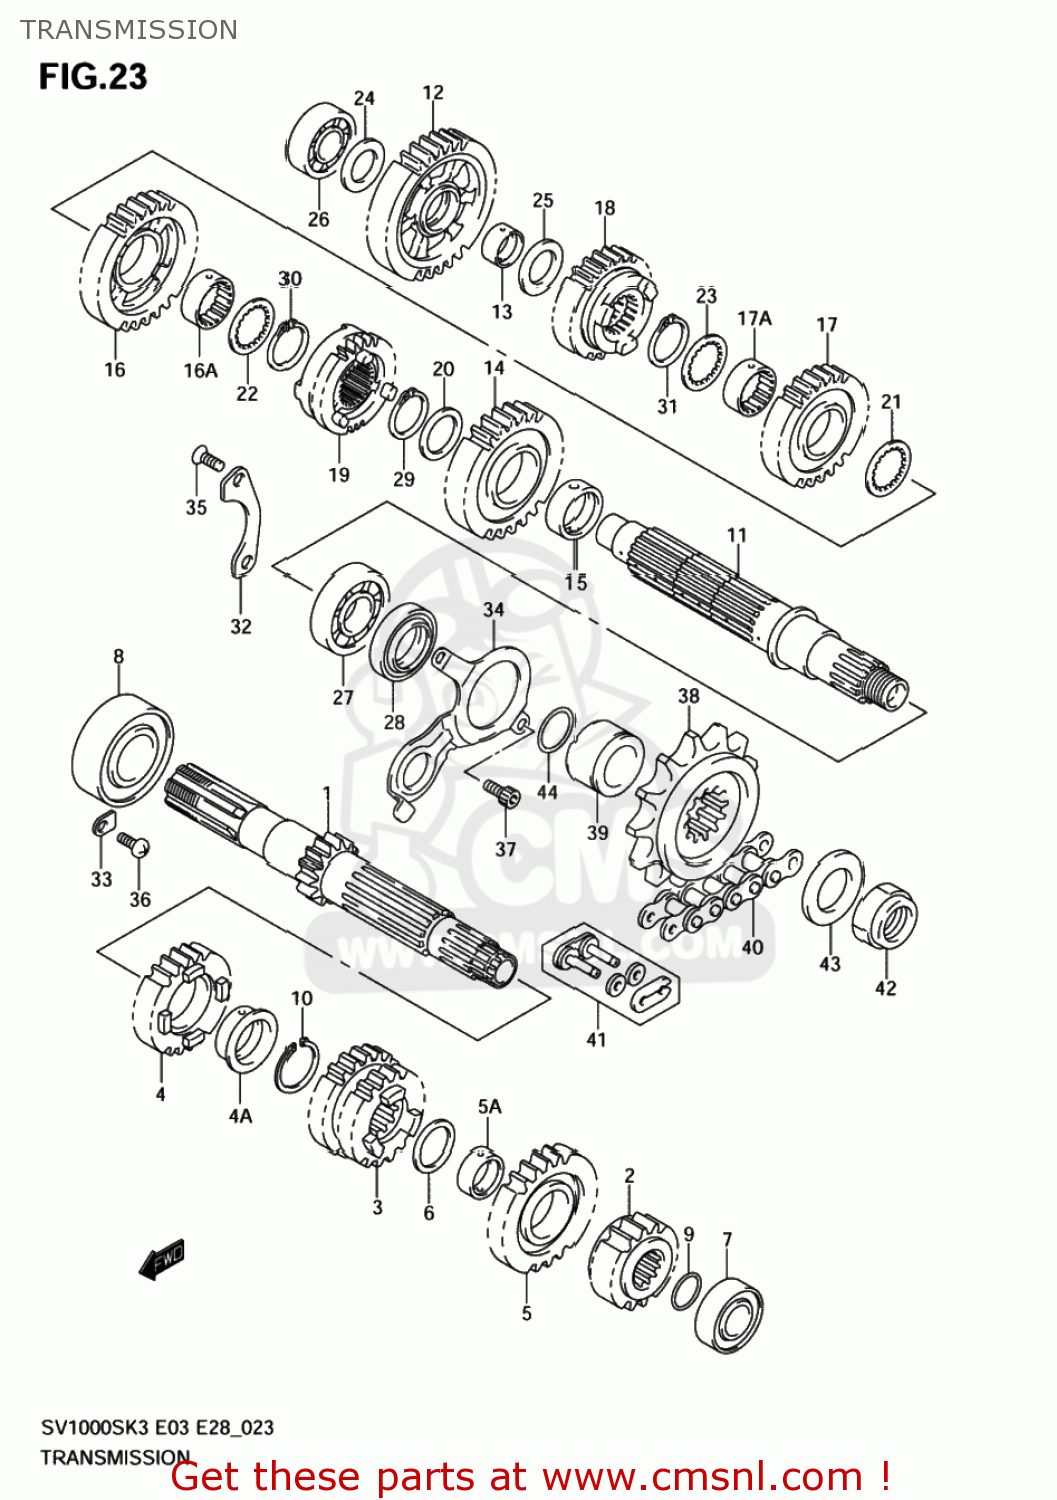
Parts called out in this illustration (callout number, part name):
1	SHAFT,COUNTER(NT:12)
2	GEAR,2ND DRIVE(NT:15)
3	GEAR,3RD & 4TH DRIVE(NT:18/22)
4	GEAR,5TH DRIVE(NT:23)
4A	BUSH,5TH DRIVE GEAR
5	GEAR,6TH DRIVE(NT:24)
5A	BUSH,6TH DRIVE GEAR
6	SHIM(22X30X1)
7	BEARING(20X47X14)
8	BEARING(25X62X17)
9	O RING(D:1.9,ID:16.6)
10	CIRCLIP
11	SHAFT,DRIVE
12	GEAR,1ST DRIVEN(NT:32)
13	BUSH
14	GEAR,2ND DRIVEN(NT:29)
15	BUSH,2ND DRIVEN GEAR
16	GEAR,3RD DRIVEN(NT:27)
16A	BUSH,3RD DRIVEN GEAR
17	GEAR,4TH DRIVEN(NT:27)
17A	BUSH,3RD DRIVEN GEAR
18	GEAR,5TH DRIVEN(NT:25)
19	GEAR,SIXTH DRIVEN (NT:24)
20	WASHER(27X36X1)
21	WASHER,LOCK
22	WASHER,3RD & 4TH DRIVEN
23	WASHER,3RD & 4TH DRIVEN
24	SHIM(20X34X1)
25	SHIM(22X34X1)
26	BEARING(20X52X15)
27	BEARING(28X68X20)
28	SEAL,OIL(38X52X8)
29	CIRCLIP
30	CIRCLIP
31	CIRCLIP
32	RETAINER,DRIVE SHAFT BEARING
33	RETAINER
34	RETAINER,DRIVE SHAFT OIL SEAL
35	SCREW(6X12)
36	SCREW
37	BOLT,STRANGER
38	SPROCKET,ENGINE(NT:17)
39	SPACER,ENGINE SPROCKET
40	CHAIN,DRIVE
41	JOINT SET,CHAIN
42	NUT
43	SHIM(25X40X1.5)
44	O RING(D:2.4,ID:23.7)
